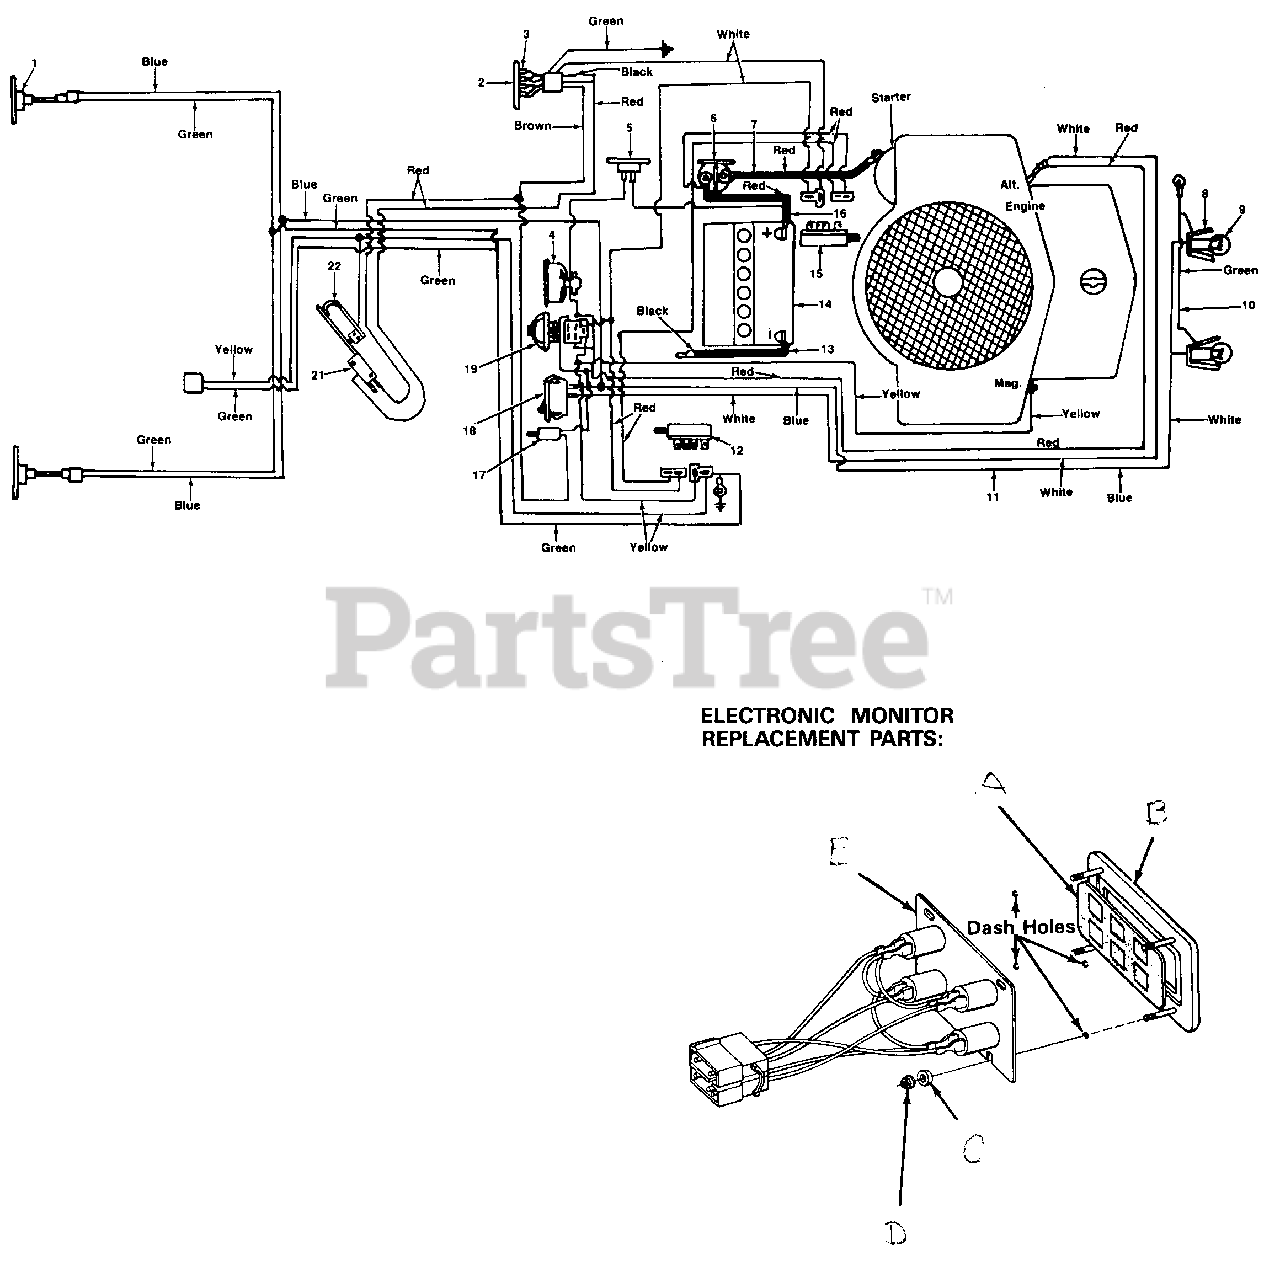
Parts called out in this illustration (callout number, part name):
1	Taillight
2	Indicator Light Ass'y.
4	Ammeter
5	Circuit Breaker
6	Solenoid
7	Wire
8	Socket
9	Bulb
10	Ground Wire
11	Wire Harness
12	Safety Switch
13	6 Ga. Black Wire 7.5" Lg.
14	12V Battery
15	Safety Switch
17	Safety Switch N.O. Black
18	Headlight Switch
19	Ignition Switch
21	Micro Switch
22	Spring Switch
